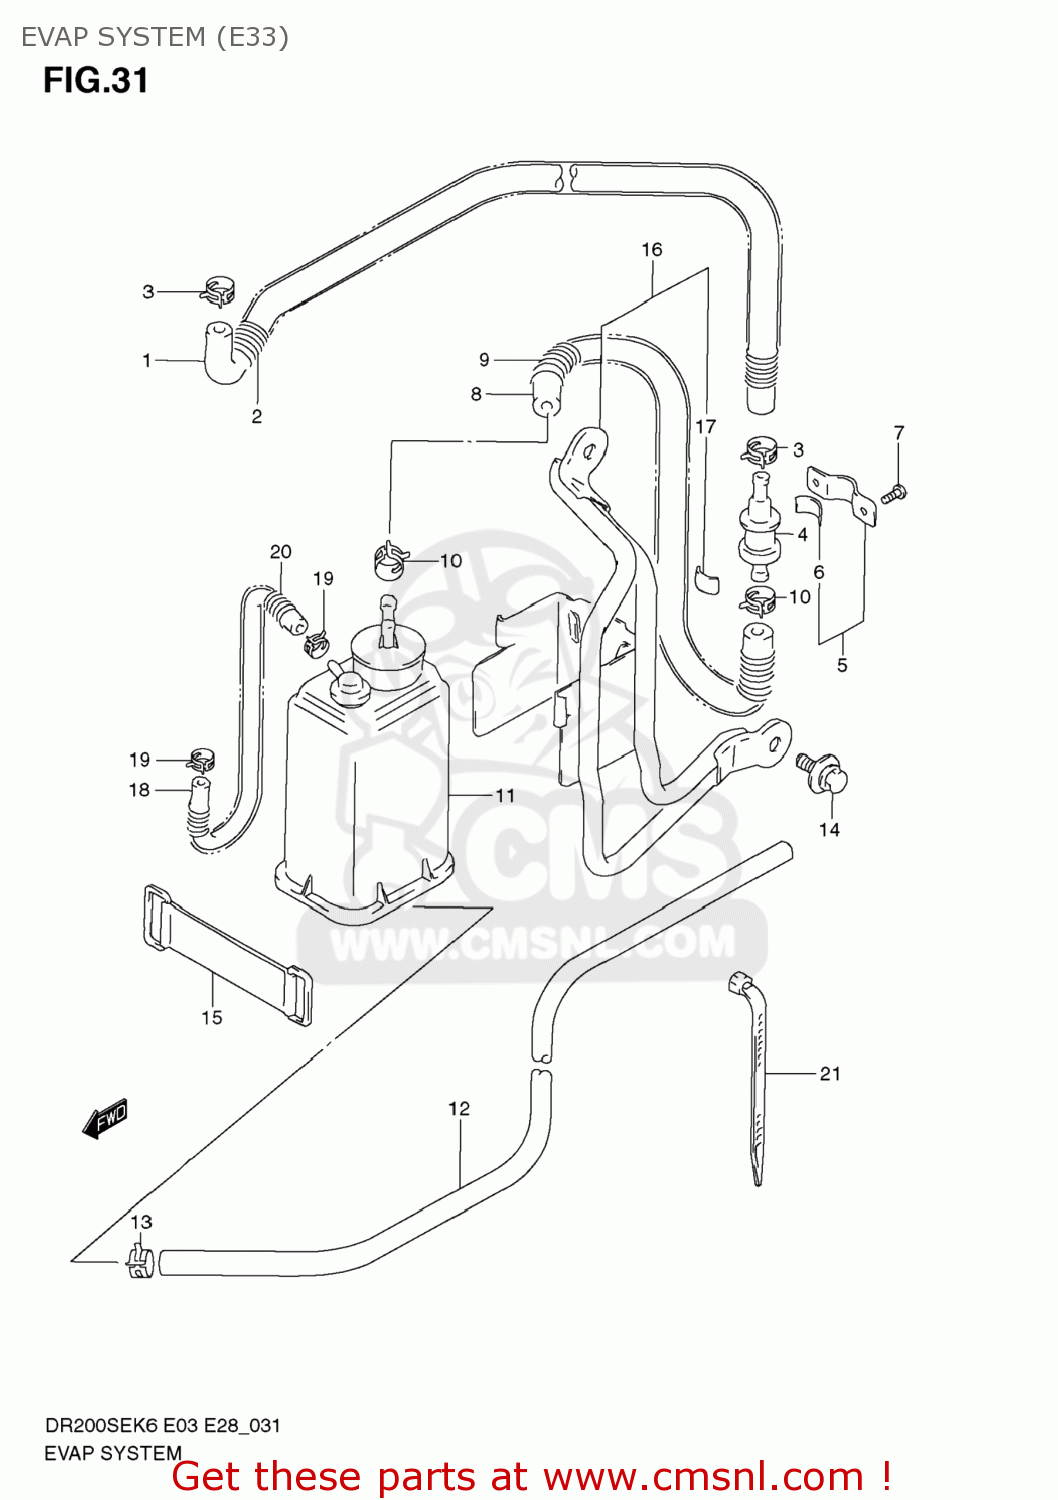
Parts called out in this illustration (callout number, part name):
1	HOSE (5.4X11.4X790)
2	SPRING
3	CLIP
4	VALVE,FUEL TANK BREATHER
5	PLATE,FUEL TANK BREATHER NO.2
6	CUSHION
7	SCREW
8	HOSE
9	SPRING
10	CLIP
11	CANISTER ASSY,CHARCOAL
12	HOSE(7X11X2000)
13	CLIP
14	BOLT(6X16)
15	BAND
16	PLATE,CANISTER
17	CUSHION
18	HOSE(3.5X7.5X600)
19	CLIP
20	SPRING
21	CLAMP(L:125)
